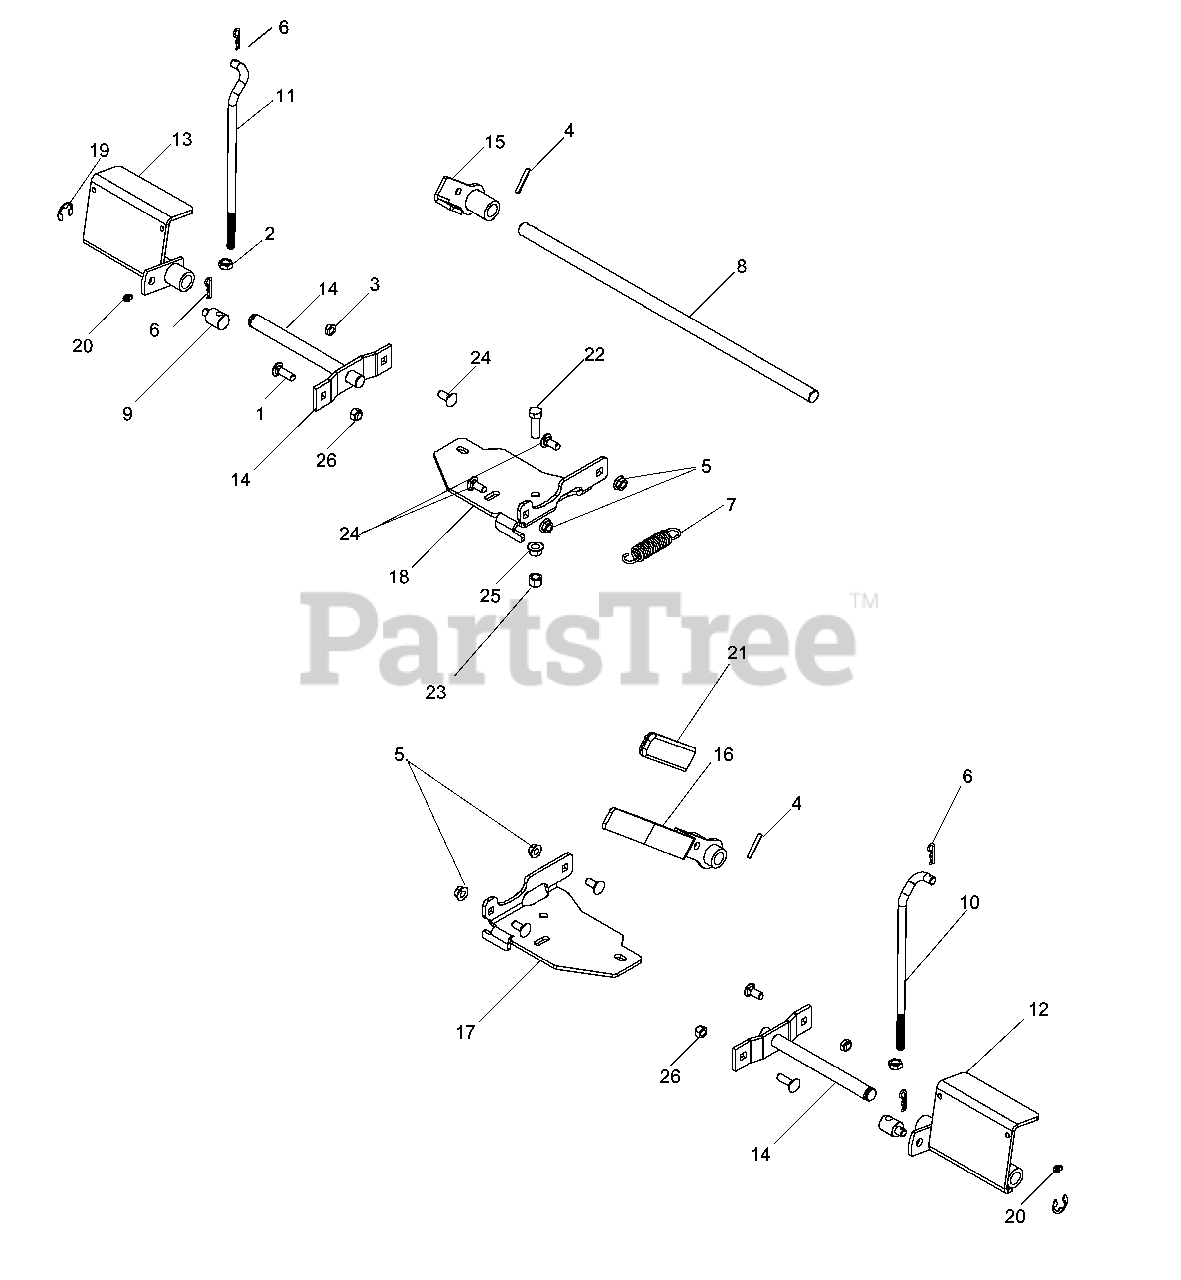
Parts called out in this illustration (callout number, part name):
1	RHSSNB 5/16C X 1.0
2	NUT 3/8-16 HEX JAM
3	5/16-18 THIN PROF NY
4	ROLL PIN 3/16 X 1-1/4
5	5/16-18 FLANGED L-NUT
6	COTTER HP .08 DIA X 1.19
7	SPRING - 3.50
8	SHAFT BRAKE
9	SWIVEL BRAKE
10	LH BRAKE LINK
11	RH BRAKE LINK
12	WLDT. BRAKE SHOE LH
13	WLDT. BRAKE SHOE RH
14	WLDT BRAKE PIVOT
15	BRAKE LINK DRILLED
16	BRAKE HANDLE DRILLED
17	BRKT. TANK MT. LH
18	BRKT. TANK MT. RH
19	RETAINING RING 5/8
20	GREASE ZERK-1/4"
21	GRIP BRAKE HANDLE
22	HCS 3/8C X 1 1/4 GR5
23	NUT 3/8-16 NYLOC
24	BOLT 5/16C X 3/4" CARRIAGE
25	NUT 3/8C WHIZ
26	NUT 5/16 NYLOC
